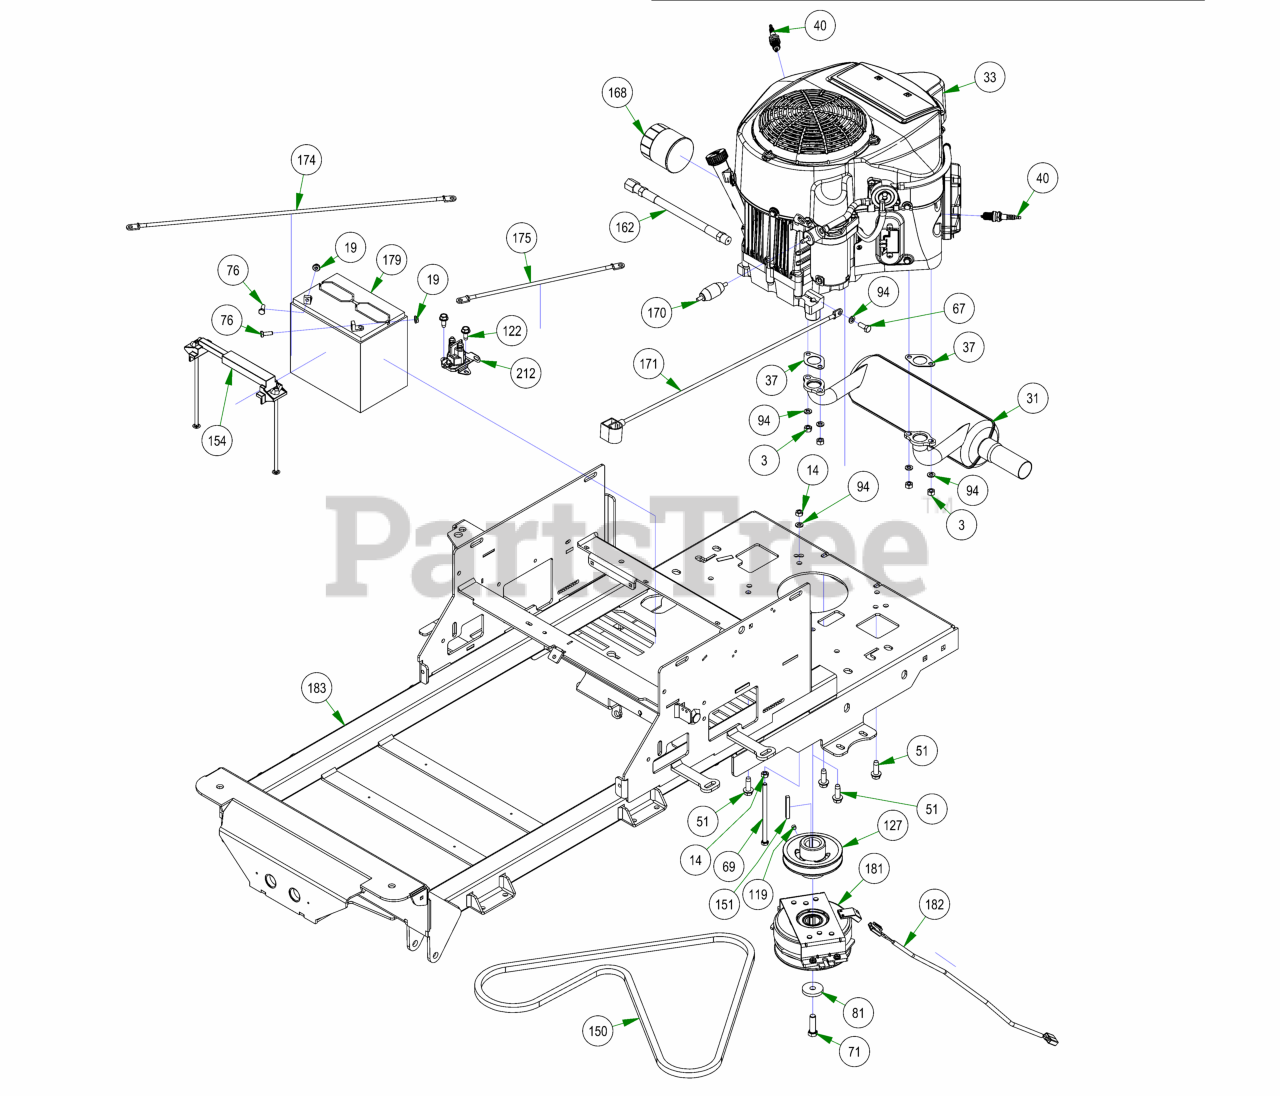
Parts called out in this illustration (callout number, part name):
3	M8-1.25 DIN 934 HEX NUT (CL.8) ZINC
14	5/16-18 HEX NUT ZINC
19	1/4-20 HEX SERRATED FLANGE NUT HARD/ZINC
31	Kawasaki Muffler 1251
33	FR 730V-S16 Kawasaki Engine 1.125" shaft-ZT
37	Exhaust Gasket
40	Spark Plug - Kawasaki
51	3/8-16 X 1-1/8HEX WASHER UNSLOT SERRATED (TRI-LOB) TRS
67	M8-1.25 X 20MM DIN 933 HEX TAP BOLT (CL 8.8) ZINC
69	5/16-18 X 5-1/2 HEX CAP SCREW (GR.5) ZINC
71	7/16-20 X 1-1/2 HEX CAP SCREW (GR.8) w/ Patch
76	1/4-20 X 3/4 HEX CAP SCREW (GR.5) ZINC
81	CLUTCH WASHER
94	5/16 SPLIT LOCKWASHER ZINC
119	5/16-24 X 1/4 SOCKET SET SCREW (CUP PT) PLAIN
122	5/16-18 X 3/4HEX WASHER SLOT (F) TCS ZINC
127	4 3/4 Motor Pulley
151	1/4 X 2 SQ MACHINERY KEY 1018 STL PLAIN
154	Hold Down Assembly
162	Oil drain Hose
168	22-26 Kaw Oil Filter FR Engine
170	Universal Inline Fuel Filter
171	24 inch Black Cable – MZ/ZT
174	24" Red Battery Cable
175	12 in red battery cable
179	SP-35 Battery
182	Clutch Pigtail
183	2022 Suspension ZT Frame - Painted
